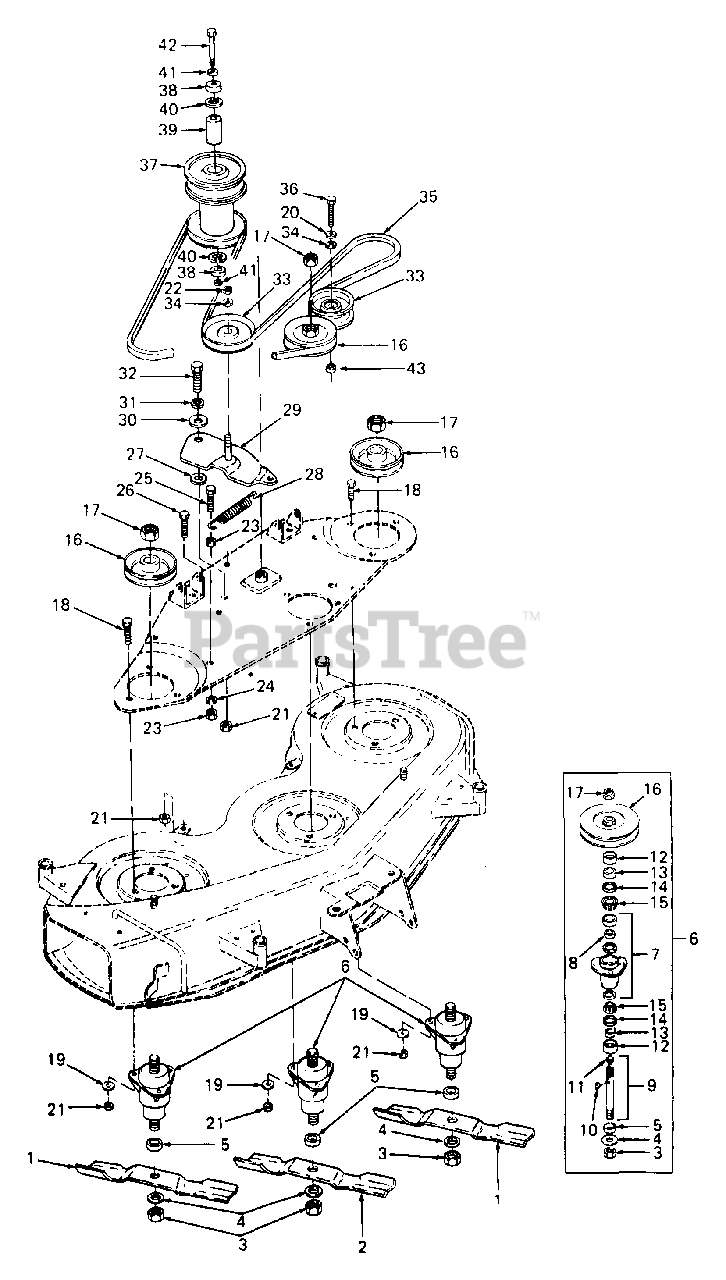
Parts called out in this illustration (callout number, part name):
1	Blade, Low Lift, 16.28 Lg
2	Blade, Low Lift, 14.88 Lg
3	Nut, Hex, 3/4-16 GR8
4	Washer, Flat, .781 X 2.0 X .105 Thk
5	Spacer, Blade
6	Spindle Service Kit
7	Housing, Spindle w/Cups
8	Spacer, Bearing
9	Kit, Shaft w/Seal
10	Key, #91 Woodruff, 1/4 X 3/4 HDN
11	Fitting, Lube, 3/16
12	Cup, Spindle HDN
13	Spacer, .755 X 1.25 X .44 Lg
14	Seal, Oil, 1.25 X 1.874 X .25
15	Cone, Bearing
16	4L V-Pulley, 4.62 OD X.75 ID
17	Nut, Hex Jam, 3/4-16
18	Screw, Hex Cap, 3/8-16 X 1.25 GR5
19	Washer, Flat, .378 X 1.0 X .127 Thk
20	Washer, Lock, 3/8 Dia
21	Nut, Hex Flanged Lock
22	Nut, Hex Center Lock, 3/8-24 GR5
23	Nut, Hex, 1/4-28
24	Washer, Lock, 1/4 Dia
25	Screw, Hex Cap, 1/4-28 X 1.25 Lg GR5
26	Screw, Hex Cap, 3/8-16 X 1.0 Lg GR5
27	Washer, Flat, .378 X 1.0 X .125 Thk HDN
28	Spring, Extension, .88 OD X 4.00 Lg
31	Washer, Bell, 3/8 Dia
32	Screw, Hex Cap, 3/8-16 X 1.25 Lg GR5
33	Idler, Flat, 3.5 OD
34	Washer, Flat, .406 X .75 X .63 Thk
35	Belt, Spindle Drive
36	Screw, Hex Cap, 3/8-16 X 1.75 Lg GR5
37	Pulley, Double
38	Bearing, Ball, .62 ID X 1.57 OD X .44 Thk
39	Spacer, Pulley, .64 ID X .88 OD X 2.37 Lg
40	Snap Ring, Internal
41	Washer, Flat, .63 ID X 1.0 OD X .63 Thk HDN
42	Bolt, Hex, 5/8-18 X 4.25 Lg GR5
43	Spacer, .380 ID X 1.00 OD X .32 Lg
